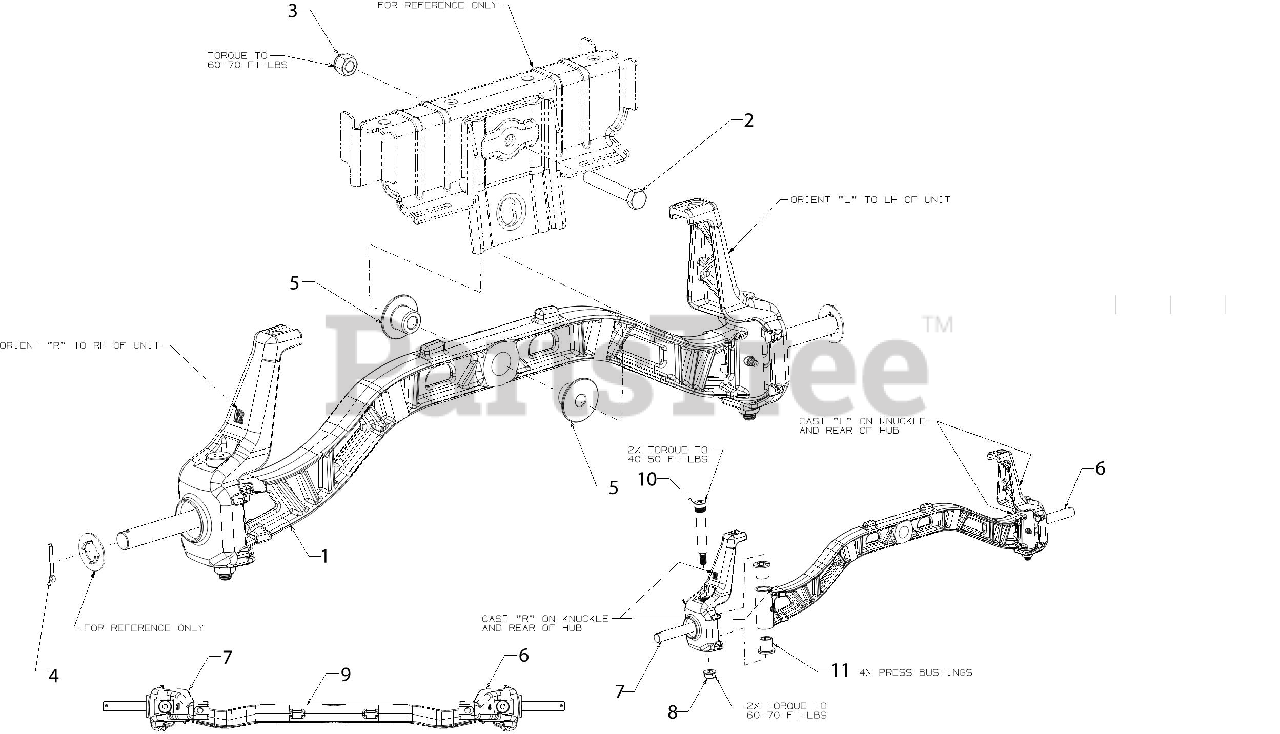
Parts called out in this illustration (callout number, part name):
1	FRONT AXLE ASSEMBLY
2	HEX SCREW 1/2-13 x 3.00
3	HEX LOCK NUT NYLON
4	COTTER PIN-5/32 DIA
5	SHOULDER SPACER
6	EPS STEERING AXLE ASSEMBLY (LH)
7	EPS STEERING AXLE ASSEMBLY (RH)
9	CAST PIVOT BAR AXLE
10	SHOULDER BOLT .75X3.92 1/2-13
11	FLANGE BEARING .75 x 1.00 x 1.12
